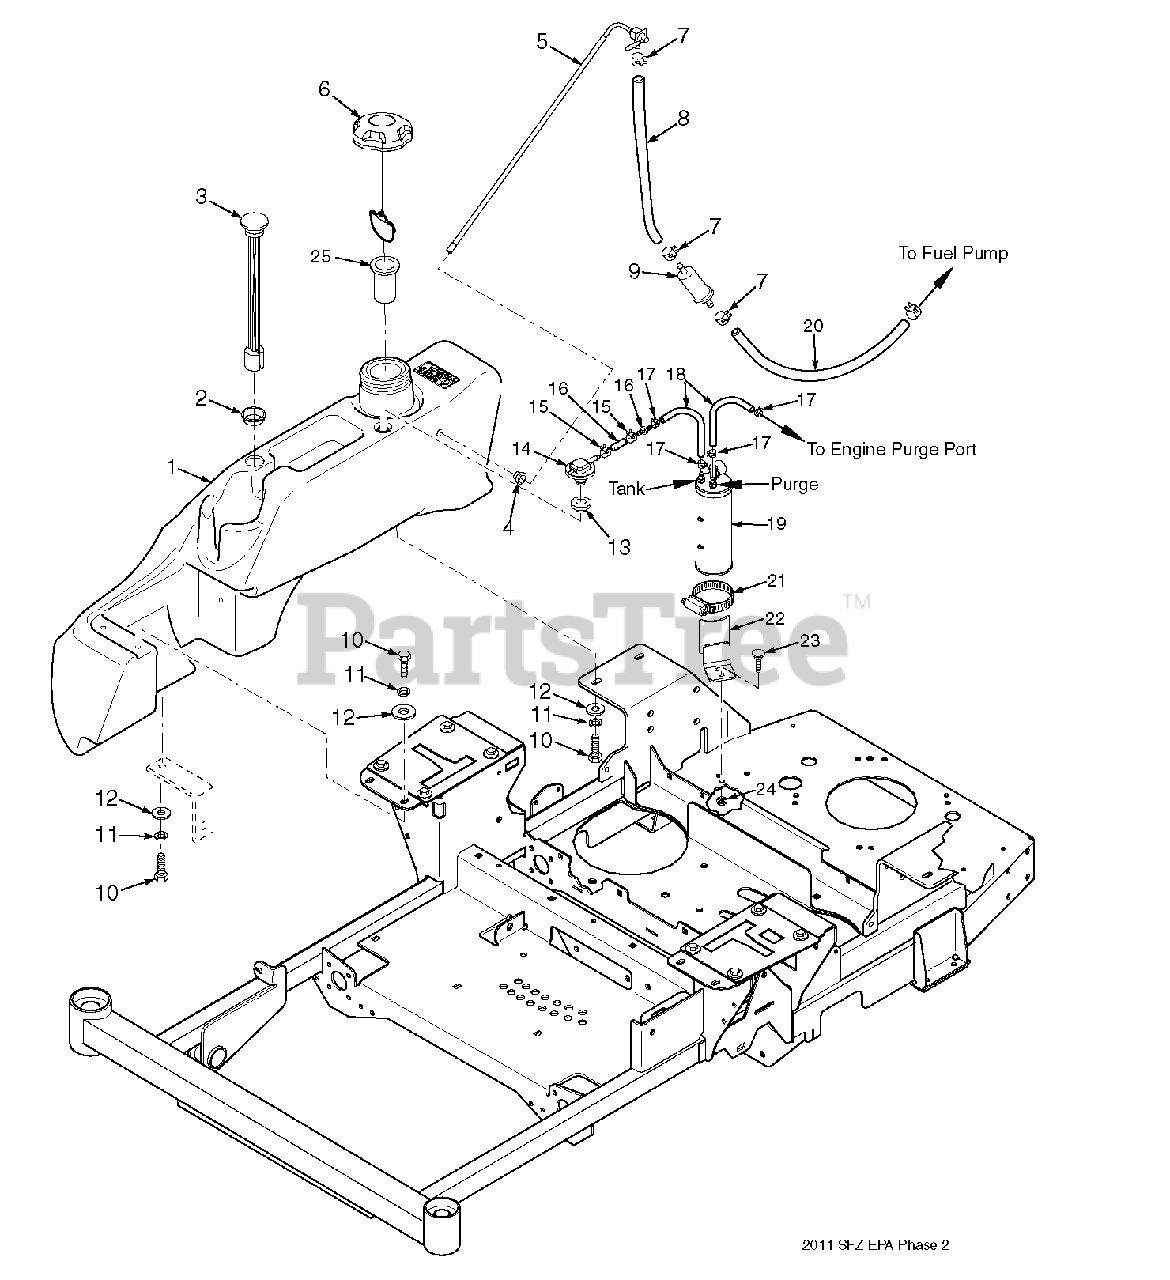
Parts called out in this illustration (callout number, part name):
1	Fuel Tank Assembly
2	Grommet
3	Fuel Gauge Assembly
4	Bushing, .56 Dia. Viton
5	Fuel Tube Assembly
6	Fuel Cap, Tethered
7	Clamp, Fuel Hose 1/4"
8	Fuel Hose, 1/4" Non-Perm
9	Fuel Filter
10	Bolt, Hex Head 5/16-18 x 3/4"
11	Lockwasher, 5/16" Spring
12	Flatwasher, 5/16-.375 x .875 x .083
13	Grommet, Viton
14	Remote Vent
15	Clamp, Fuel Hose 7/32"
16	Hose, 1/4" Vapor Recovery
17	Clamp, Vapor Recovery Hose
18	Hose, 3/16"
19	Carbon Canister
20	Fuel Hose
21	Clamp, Hose
22	Bracket Weldment
23	Bolt, Carriage 5/16-18 x 3/4"
24	Nut, Serrated Flange 5/16-18
25	Tube, Fuel Tank Insert
26	Mender, 1/4 x 3/16 w/0.02 Hole
